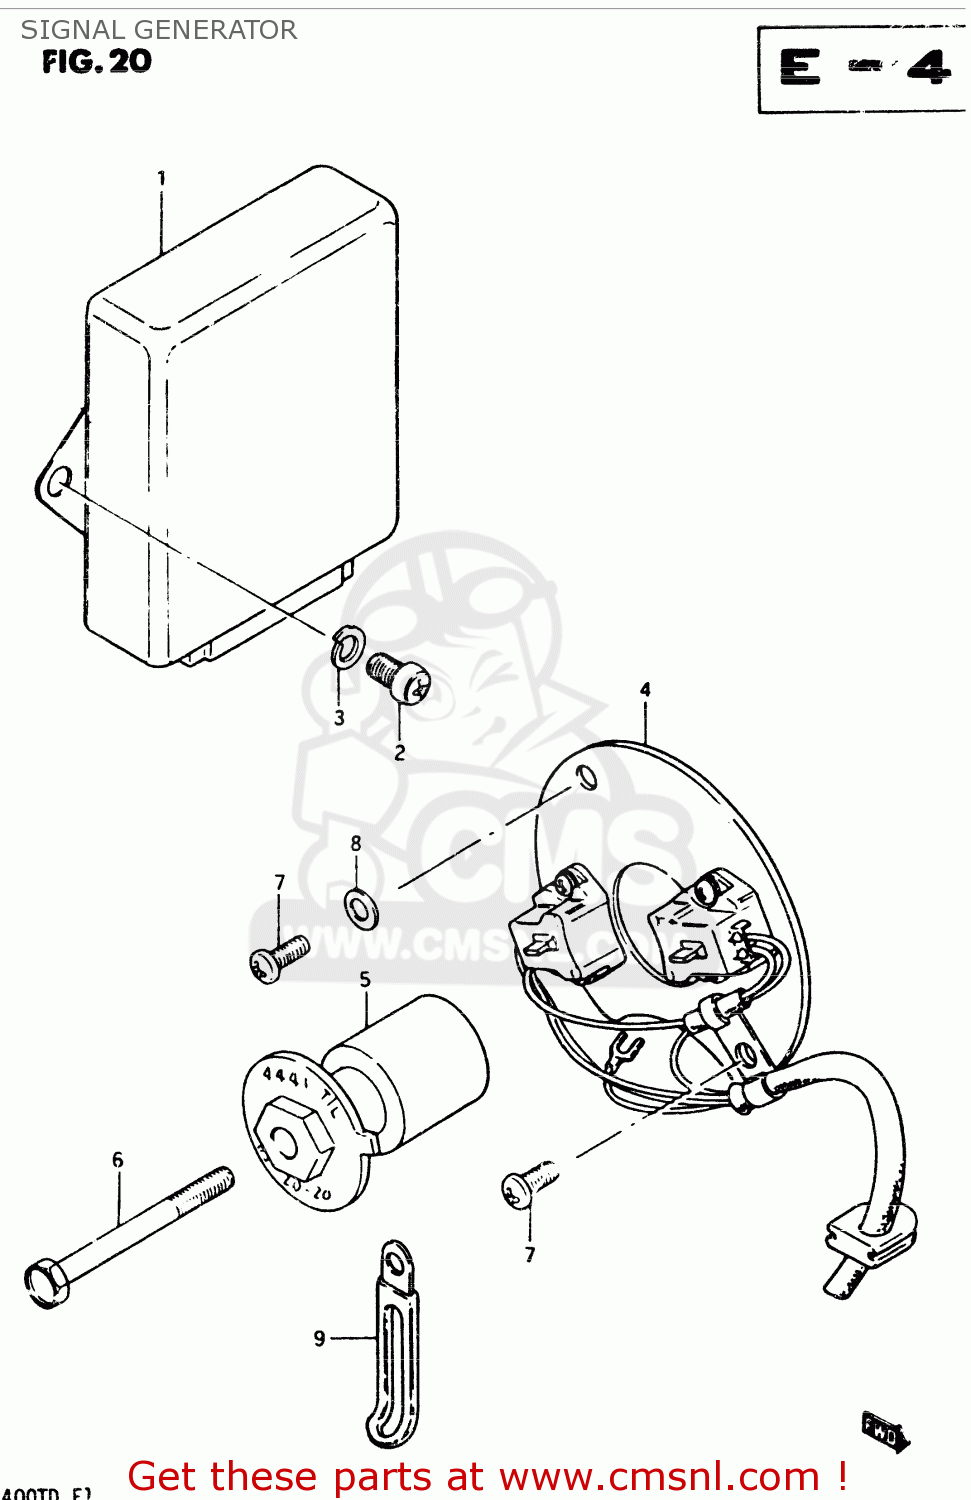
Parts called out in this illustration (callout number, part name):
1	IGNITER UNIT A
2	SCREW
3	LOCK WASHER
4	SIGNAL GENERATOR ASSEMBLY
5	ROTOR, SIGNAL
6	BOLT 6X60
7	SCREW(5X12)
8	WASHER
9	CLAMP L:35
